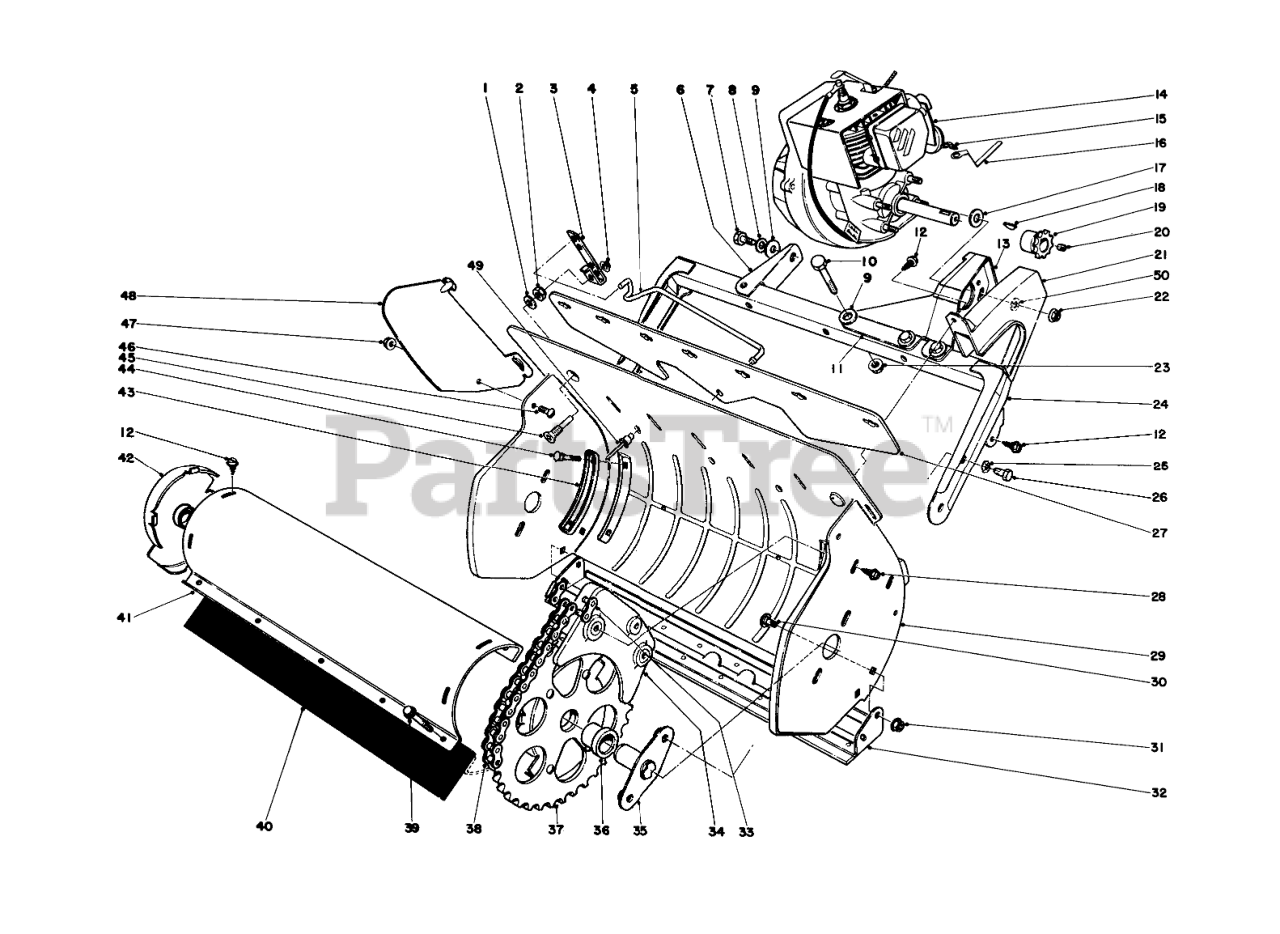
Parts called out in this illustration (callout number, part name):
1	WASHER-FLAT
2	NUT-LOCK, NI
3	Bracket-Vane Adj.
4	NUT-SPEED
5	Linkage Vane Adj.
6	Bracket
7	SCREW-HH
8	WASHER-LOCK/EXT
9	WASHER-FLAT
10	SCREW-HH
11	Bracket Engine
12	SCREW-HWHTF
13	Bracket Engine
14	Engine Mod. #AH520 Type No. 1401G
15	Cotter Pin
16	Choke Strap
17	WASHER-PLAIN
19	SPROCKET
20	SCREW-SET, HSH
21	Chain Guard
22	NUT-HHF
23	NUT-LOCK, HHF
24	Frame Assembly
25	Washer
26	Screw
27	Vane Mount
28	Screw
29	Housing
30	SCREW-CARRIAGE
31	NUT-KEPS
32	Skid
33	LINK-CONNECTING, NO. 35
34	Stripper
35	Rotor Shaft
36	ROTOR BUSHING
37	End Cap Assembly L.H. (Incl. Ref. #36)
38	CHAIN
39	Screw
40	ROTOR BLADE
41	ROTOR SHELL
42	End Cap Assembly R.H. (Incl. Ref. #36)
43	Handle Plate
44	SCREW-CARR
45	Screw
46	SCREW-PTH
47	NUT-LOCK, FLANGE
48	Vane
49	Pop Pivot
50	Lockwasher
